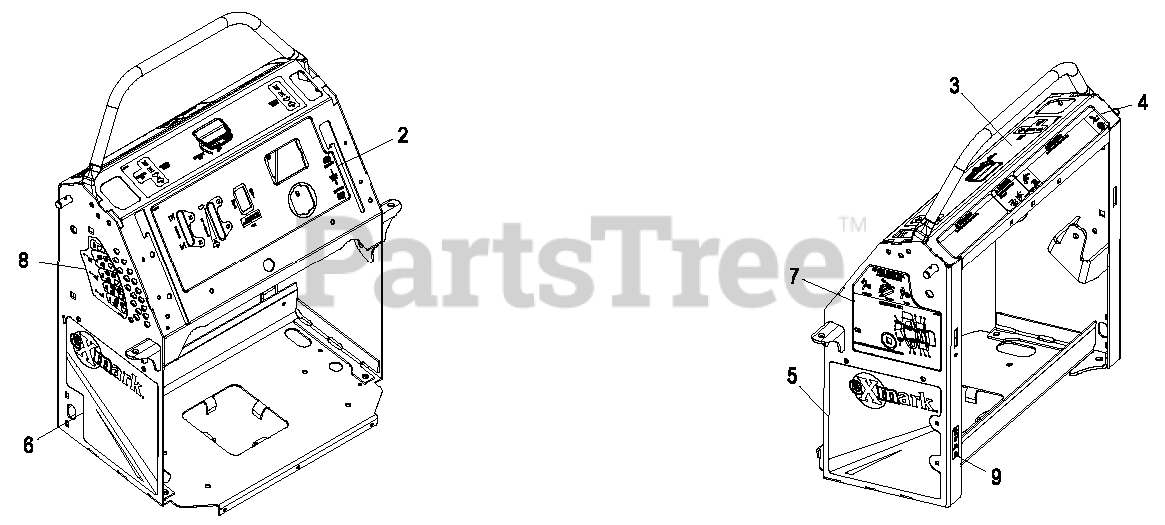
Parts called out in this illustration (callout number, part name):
3	DECAL-MOTION CONTROL
6	DECAL-RH PANEL
8	DECAL-HEIGHT OF CUT
9	DECAL-FUSE
